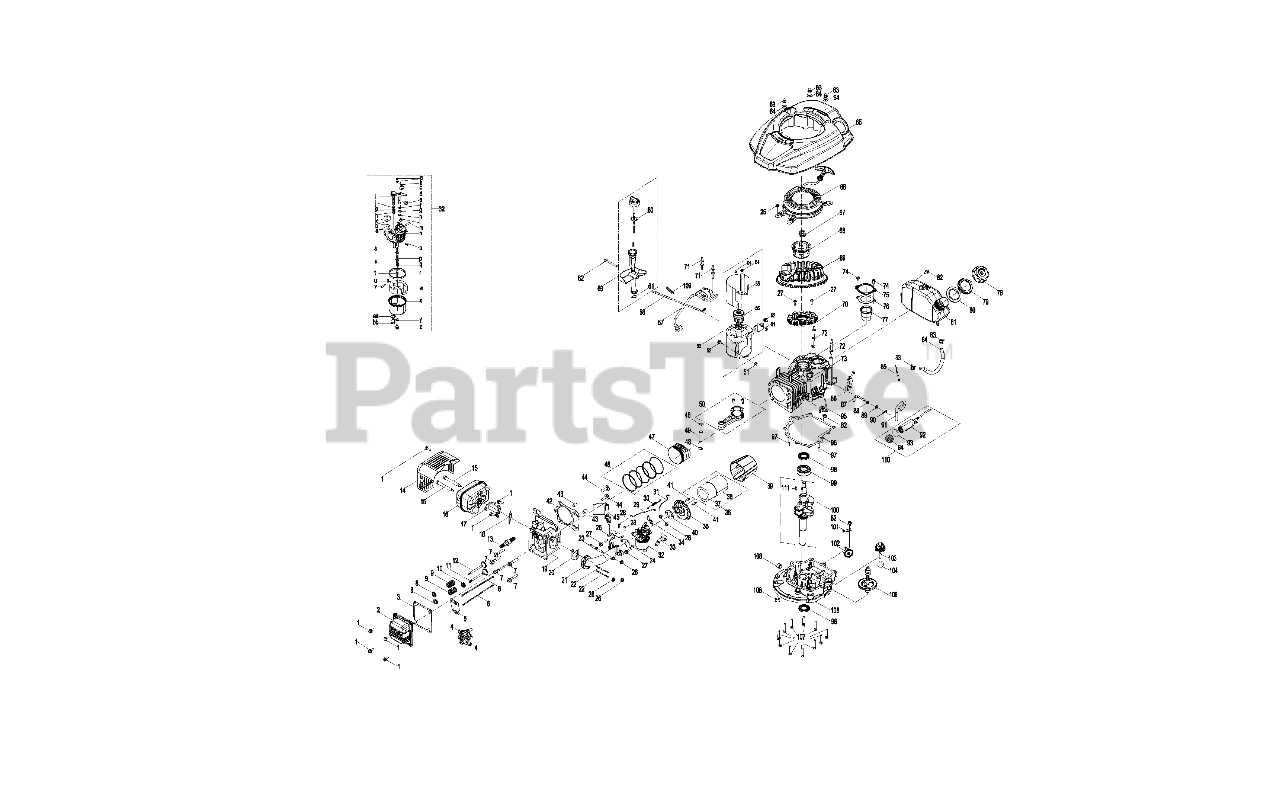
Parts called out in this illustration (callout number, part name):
1	BOLT M6 x 16
2	VALVE OHV COVER
3	VALVE COVER GASKET
4	STUD M6-0.75 x 25
4	RKRA-ENGINE OHV 19
5	PUSH ROD GUIDE
6	PUSH ROD TUBE 195
7	SCREW M8-1.25 x 45:CL5.8
8	SPRING VALVE RET
9	COMPRESSION SPRING 16ID x 33.83
10	INTAKE VALVE SEAL
11	INTAKE VALVE SEAL
12	EXHAUST VALVE
13	SPARK PLUG
14	MUFFLER GUARD
15	SHOULDER SCREW 9.5 x 69 M6-1
16	MUFFLER
17	EXHAUST TUBE ASSEMBLY
18	EXHAUST GASKET
19	CYLINDER HEAD
20	MANIFOLD GASKET
21	MANIFOLD ASSEMBLY
22	STUD - M6-1.3 ZS
23	STUD M6-1 x 30.5 LG
24	CARBURETOR GASKET
25	AIR VANE SUPPORT
27	BOLT M6-1 x 25 GR8.8
28	SCREW M5-2.2 x 16
29	CHOKE CONTROL ROD
30	EXTENSION SPRING .75 DIA x 76.5
31	THROTTLE CONTROL ROD
32	CARBURETOR ASSEMBLY-CHOKE 195
33	BREATHER TUBE
34	GOVERNOR SPEED ADJUSTMENT BRACKET
35	AIR FILTER BASE
36	AIR FILTER ASSEMBLY
37	ELEMENT
38	ELEMENT
39	AIR FILTER COVER
40	MANIFOLD GASKET
41	SCREW M5-.8 x 20
42	HEAD GASKET
44	TPT-CAM 195
45	CHOKE VANE
47	ENGINE PISTON 71MM
48	WRIST PIN CLIP 15M
49	TUBE-14.3 OD x 10.5 ID x 9.75LG
50	CONNECTING ROD ASSEMBLY
51	FLAT WASHER
52	BOLT M6-1 x 25 GR8.8
53	STARTER ASSEMBLY
55	GEAR COVER
56	ELECTRIC STARTER MOTOR
57	IGNITION MODULE
58	WIRE HARNESS
59	DIPSTICK ASSEMBLY
60	O-RING 21ID x 2.8 THK
61	O-RING 15.6 ID x 1.78 DIA
62	SCREW M6-1:50:CL5.
63	ACORN NUT
64	SHROUD SPACER
65	ELECTRIC START ENGINE SHROUD
66	RECOIL START ASSEMBLY
67	FLYWHEEL NUT
70	ALTERNATOR ASSEMBLY
71	STUD M5-8:22
72	STUD-M6-1:40 LG
73	CRANKCASE ASSEMBLY
74	SCREW M6-1 x 16
75	BREATHER COVER
76	BREATHER GASKET
77	BREATHER BODY ASSEMBLY
78	FUEL CAP ASSEMBLY
79	FUEL TANK NUT
80	FUEL TANK LOWER GROMMET
82	BOLT M6-1 x 12 GR8.8
83	HOSE CLAMP
84	FUEL HOSE, 6.3x12.5x230
85	FUEL FILTER
86	GOVERNOR CONTROL ARM BRACKET
87	GOVONOR CONTROL ROD
88	GOVERNOR SEAL
89	FLAT WASHER 6.8 x 16 x .4
90	COTTER PIN
92	CARBON CANISTER ASSEMBLY
93	CARBON CANISTER FILTER
94	CARBON CANISTER FILTER CAP
95	CHOKE OVER RIDE ROD ASSEMBLY
96	CRANKCASE GASKET
98	OIL SEAL-25 x 41.25 x 6
100	CRANKSHAFT-END 195 25M
101	OIL SLINGER SUPPORT BRACKET
102	OIL SLING GEAR ASSEMBLY
103	GEAR ASSEMBLY
104	FLAT WASHER 6.8 x 16 x .4
105	CAM SHAFT ASSEMBLY
106	CRANKCASE COVER
107	HHFLG M6-1 x 35 CL8.8
108	ENGINE PLUG 3/8 NPT
109	FLEXIBLE CLAMP
110	CARBON CANISTER
111	FLYWHEEL KEY
